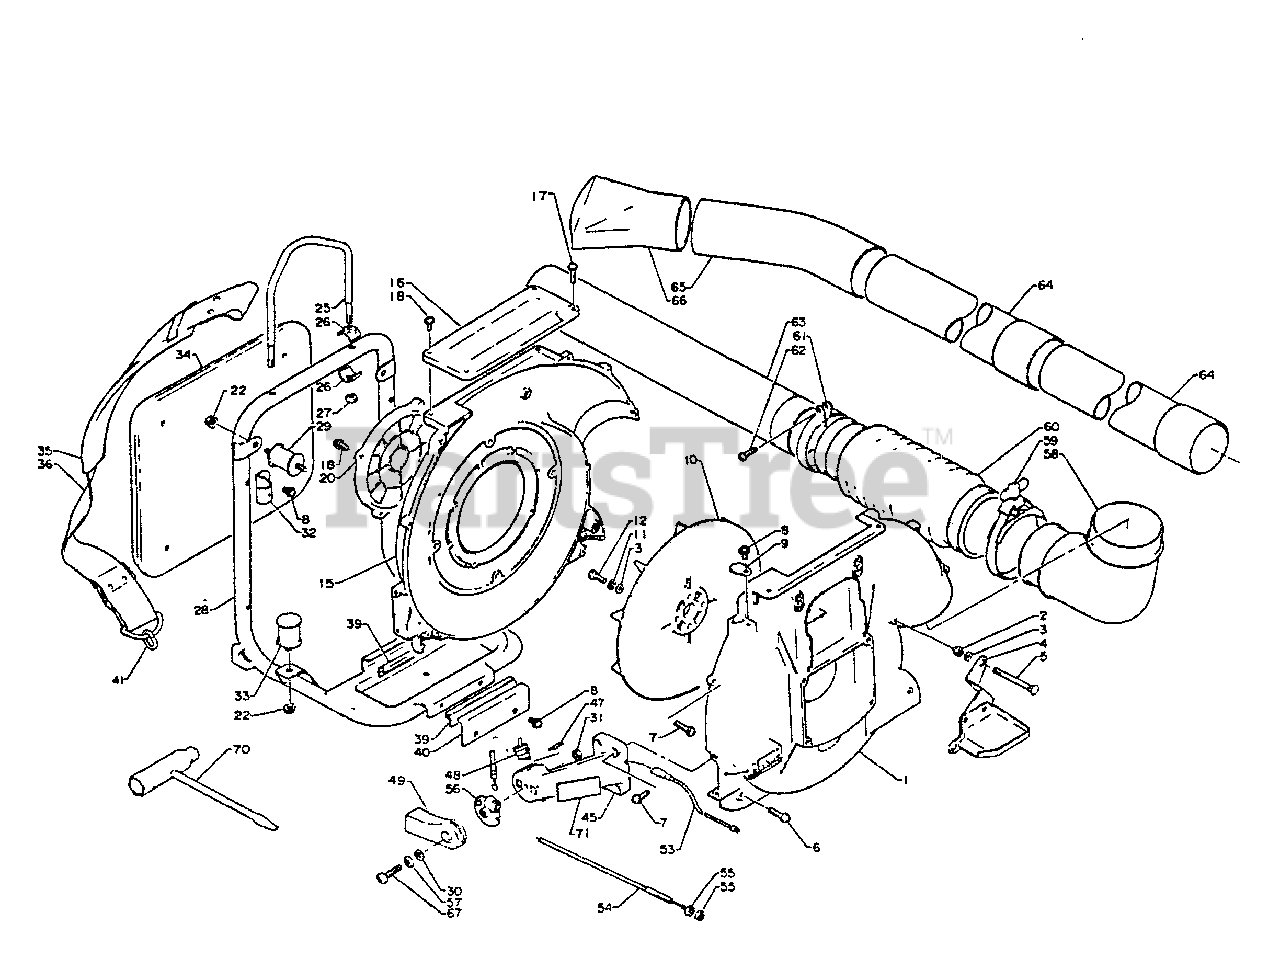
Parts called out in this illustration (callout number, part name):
1	COVER, FAN - OUTER
2	NUT - 5 -- CAP
3	WASHER, FLAT 5.5×10×0.8
4	BRACKET, MUFFLER COVER
6	SCREW 5×25
7	SCREW 5×20
8	SCREW 5×10
9	PLUG
11	WASHER, SPRING 5
12	BOLT - 5×16
15	COVER, FAN - INNER -- ORANGE
16	PLATE
17	SCREW 6×20
18	SCREW 6×15
20	SHIELD, DEBRIS
22	NUT, FLANGE M6
27	LOCKNUT - 6
28	FRAME, BACKPACK
30	WASHER 6.5×11.5×0.8
31	NUT, HEX M6
32	BRACKET, CUSHION
34	CUSHION, BACKPACK
35	HARNESS
36	BACKPACK STRAP ASSY
39	CUSHION, FUEL TANK
40	BRACKET, FUEL TANK
41	RING, STRAP
45	MOUNT, THROTTLE LEVER
47	LABEL, ON-OFF
48	IGNITION SWITCH ASSY
49	CONTROL, THROTTLE
54	CABLE, THROTTLE
58	TUBE, BLOWER - ELBOW
60	TUBE, FLEXIBLE
61	CLAMP KIT
62	SCREW 5×25
63	TUBE, BLOWER - STRAIGHT
64	TUBE, BLOWER - STRAIGHT
65	TUBE, BLOWER - CURVED
66	NOZZLE - FAN HEAD
67	SCREW 6×25
70	T-WRENCH 10×19 MM
71	LABEL - CAUTION
74	LABEL - ECHO
75	LABEL - NOISE
